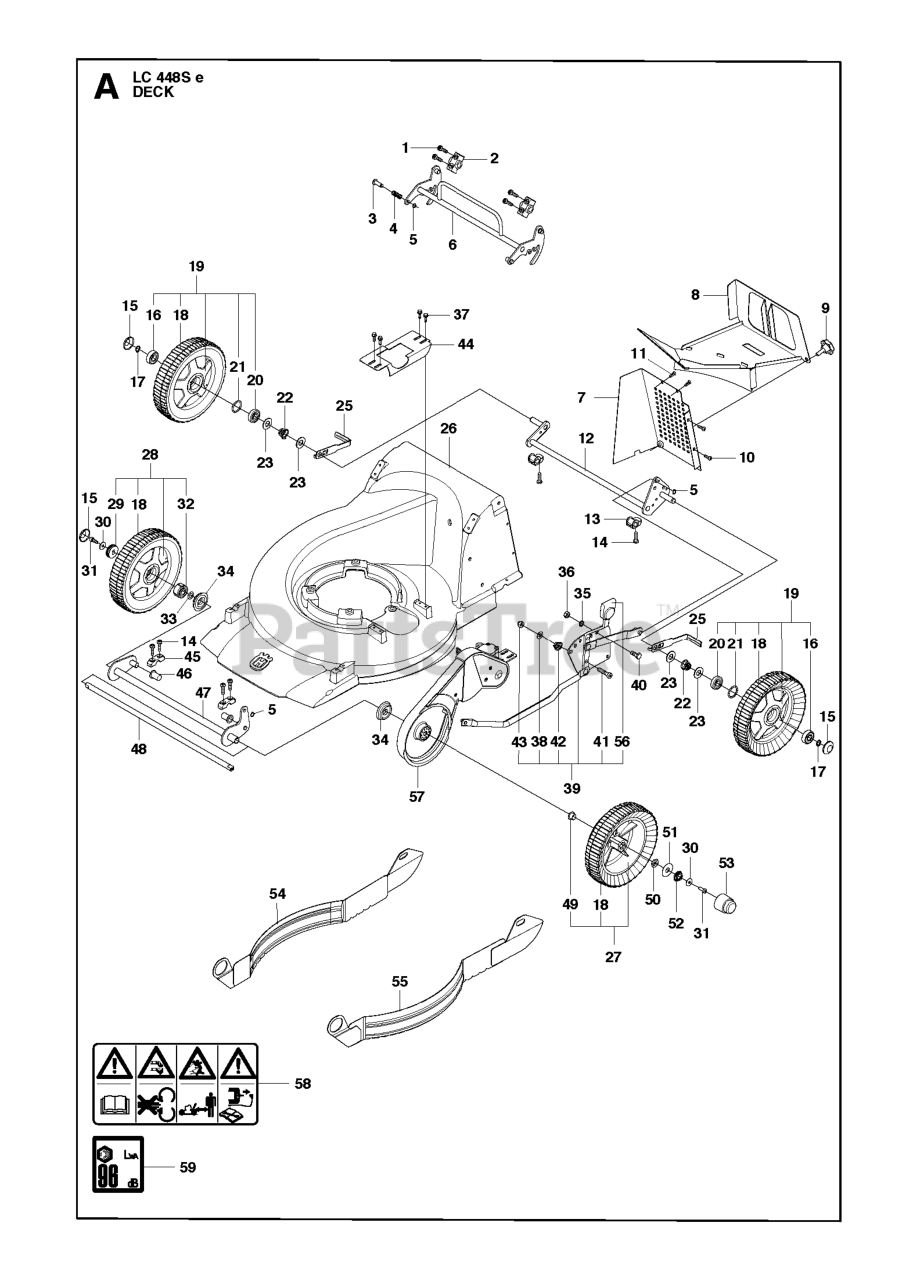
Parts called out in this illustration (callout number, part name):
5	RETAINING RING SGA 8
36	NUT
43	LOCKNUT M8
